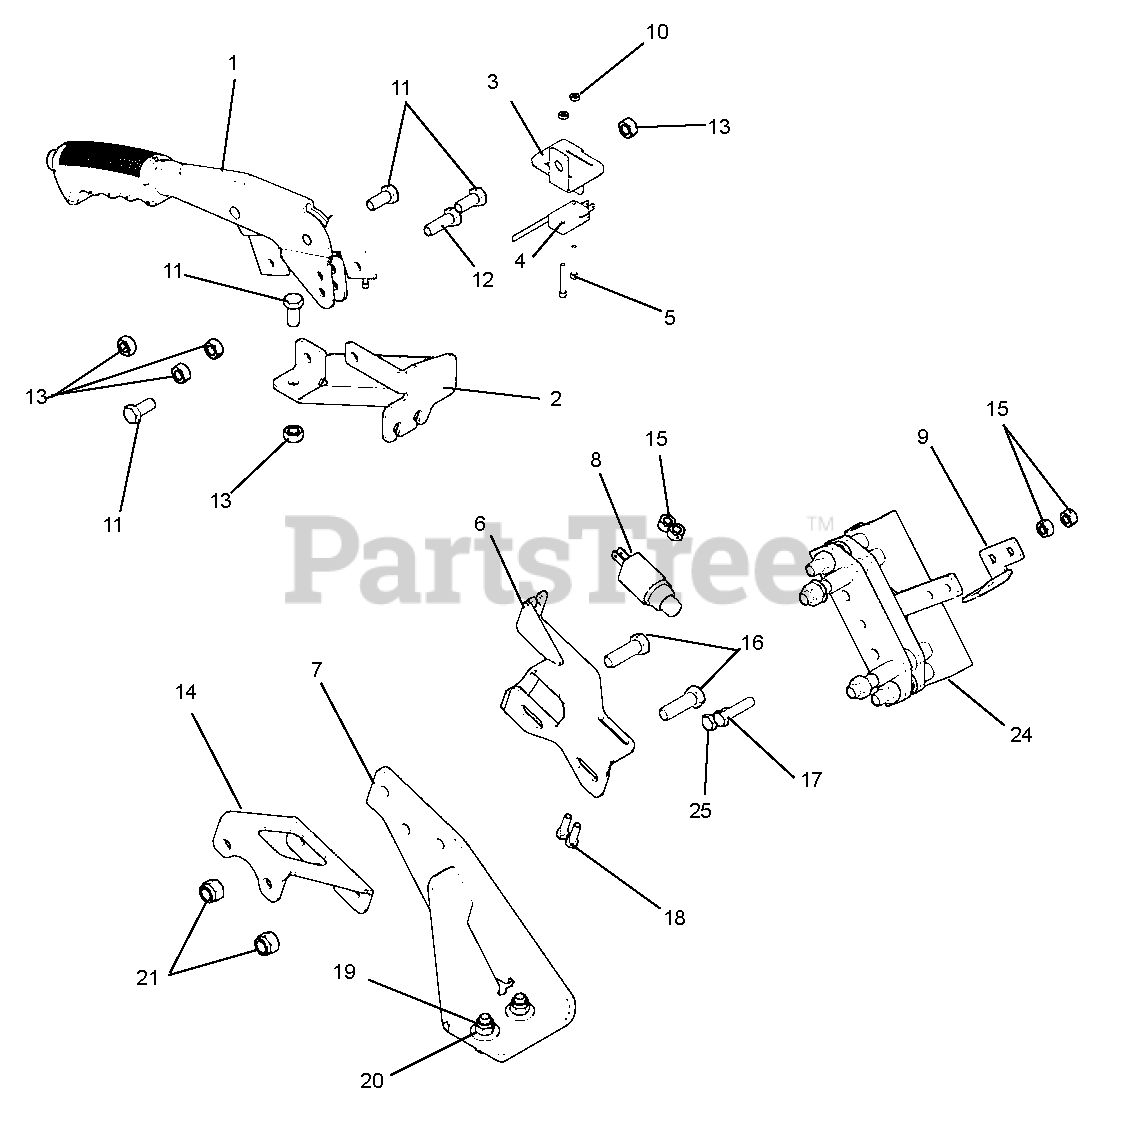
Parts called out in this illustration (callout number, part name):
1	PARK BRAKE LEVER
2	BRACKET, E-BRAKE MNT
3	BRACKET, PARK SWITCH
4	PARK BRAKE MICRO-SWITCH
5	HSHCS #4-40 X 1
6	CABLE MNT, PARK BRAKE
7	BRACKET, CALIPER MNT
8	SWITCH, (N.O.) RUBBER SEALED
9	MOUNT, SWITCH, PARK BRAKE
10	NUT, HEX 4-40 GR5 YWZC
11	BOLT, HEX .31-18 X .75 GR5 YWZC
12	BOLT, HEX .31-18 X 1.00 GR5 YWZC
13	NUT, HEX CENTER LOCK .31-18
14	BRACE, CALIPER MNT, P-BRAKE
15	NUT, LOCK CENTER H10-24 YWZC
16	BOLT, HEX .38-16 X 1.25 GR5 YWZC
17	BOLT, HEX .25-20 X 1.25 GR5 YWZC
18	BOLT, HEX 10-24 X .75 PL GR2
19	NUT, HEX NYLOCK .312-18
20	WASHER, FLAT STEEL .38 X .875 X .083 YWZC
21	NUT, HEX NYLOCK .38-16
24	BRAKE CALIPER
25	BOLT, HEX .25-20 X .75 GR5 YWZC
